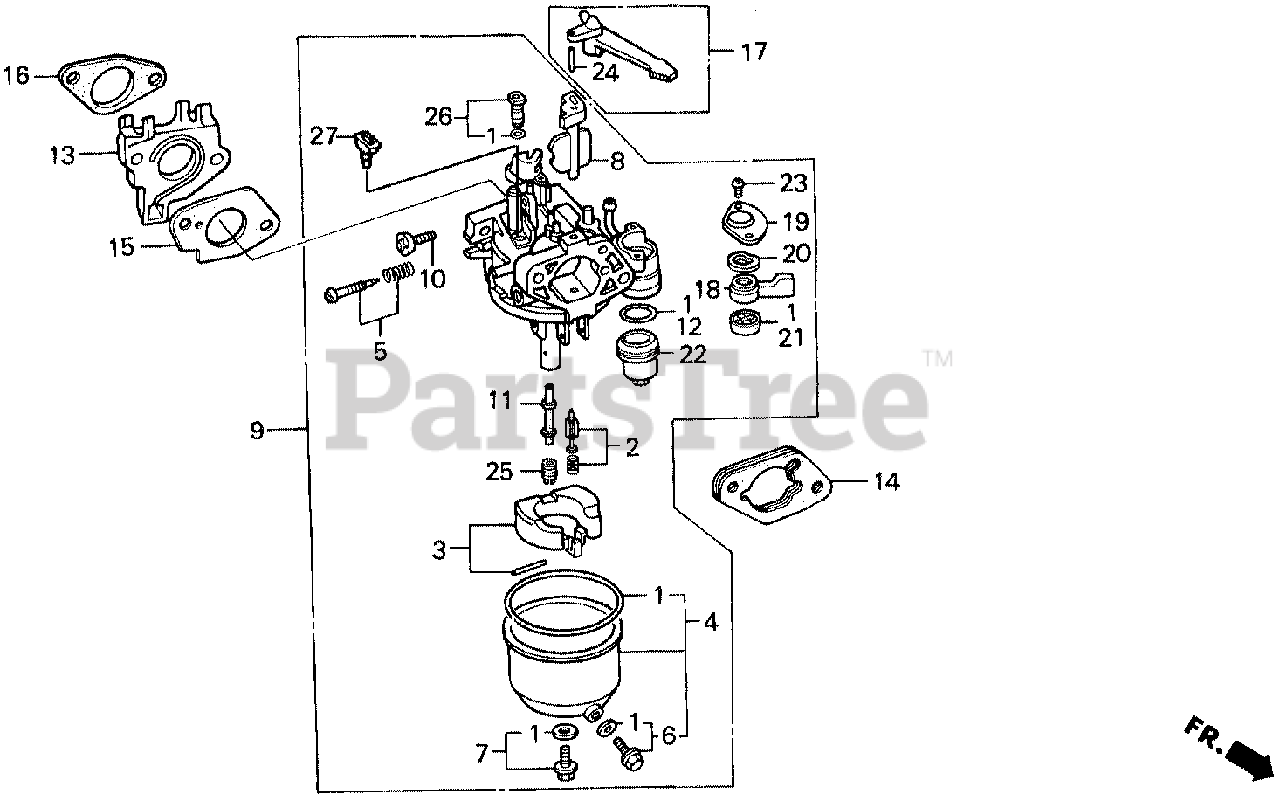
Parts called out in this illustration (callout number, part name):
1	GASKET SET
2	VALVE SET, FLOAT
3	FLOAT SET
4	CHAMBER SET, FLOAT
5	SCREW SET, PILOT
5	SCREW SET
6	SCREW SET, DRAIN
7	SCREW SET B
8	CHOKE SET
9	CARBURETOR ASSY. (BE34C A)
9	CARBURETOR ASSY. (BE80D B)
9	CARBURETOR ASSY. (BE34B C)
10	SCREW, THROTTLE STOP
11	NOZZLE, MAIN
12	GASKET, FUEL STRAINER CUP
13	INSULATOR, CARBURETOR
14	SPACER, CARBURETOR
15	GASKET, CARBURETOR
16	GASKET, INSULATOR
17	LEVER, CHOKE (STD)
18	LEVER, VALVE
19	PLATE, LEVER SETTING
20	SPRING, VALVE LEVER
21	GASKET, VALVE
22	CUP, FUEL STRAINER
23	SCREW, PAN (3X6)
23	SCREW, PAN (3X8)
24	PIN, SPRING (2X12)
25	JET, MAIN (#92)
25	JET, MAIN (#95)
25	JET, MAIN (#98)
25	JET, MAIN (#90)
26	JET SET, PILOT (#35)
26	JET SET, PILOT (#45)
